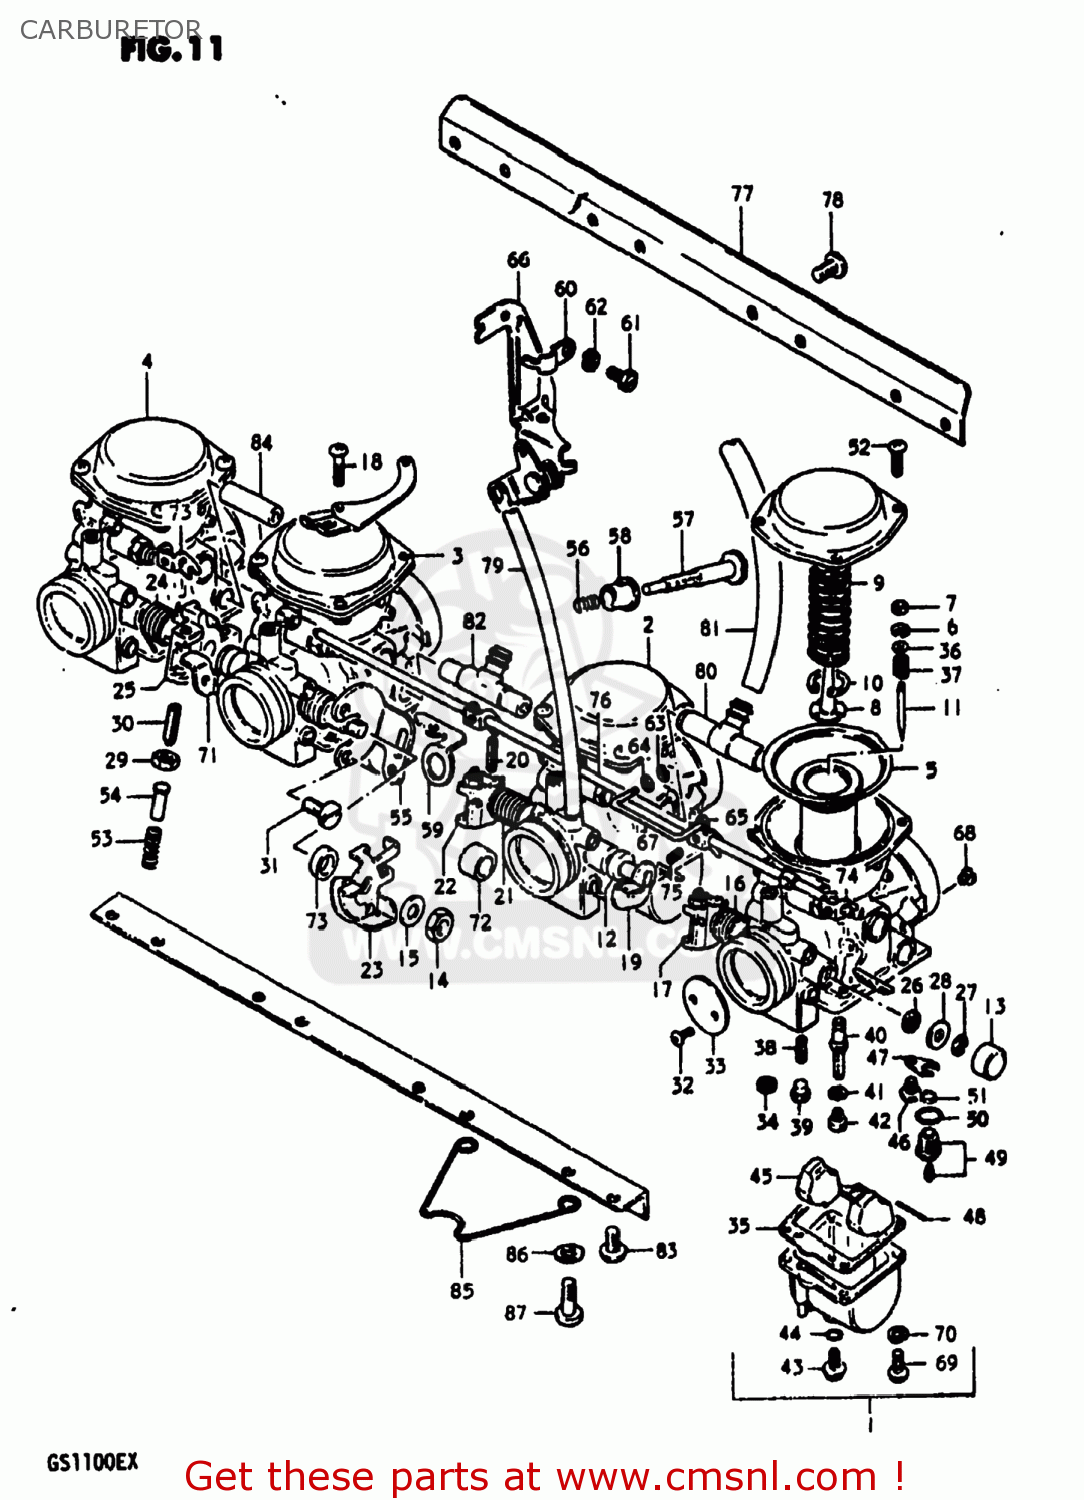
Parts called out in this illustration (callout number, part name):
1	CARBURETOR ASSEMBLY
2	CARBURETOR ASSEMBLY NO.2
3	CARBURETOR ASSEMBLY
4	CARBURETOR ASSEMBLY
5	DIAPHRAGM ASSEMBLY
6	CLIP,NEEDLE
7	RING
8	HOLDER,GUIDE
9	SPRING
10	E RING
11	NEEDLE,JET
12	GASKET
13	CAP
14	NUT
15	WASHER
16	SPRING,THROTTLE SHAFT
17	SHAFT,THROTTLE
18	SCREW
19	SHAFT,THROTTLE
20	PIN,THROTTLE SHAFT
21	SPRING,THROTTLE SHAFT
22	LEVER,THROTTLE SHAFT
23	LEVER ASSEMBLY,THROTTLE
24	SPRING,THROTTLE SHAFT
25	SHAFT,THROTTLE
26	SEAL
27	E RING
28	GASKET,THROTTLE SHAFT (NAS)
29	NUT
30	SCREW
31	SCREW
32	SCREW
33	VALVE,THROTTLE (BUTTERFLY)
34	GASKET (NAS)
35	GASKET,FLOAT CHAMBER (NAS)
36	WASHER
37	SPRING
38	JET,PILOT
39	PLUG,NEEDLE JET
40	JET,NEEDLE
41	WASHER,NEEDLE NOZZLE
42	JET,MAIN(107.5)
43	PLUG,DRAIN
44	GASKET (NAS)
45	FLOAT
46	SCREW
47	PLATE
48	PIN,FLOAT
49	VALVE ASSEMBLY,NEEDLE
50	O-RING,NEEDLE VALVE
51	FILTER
52	SCREW
53	SPRING,THROTTLE SCREW
54	PIN,THROTTLE LEVER
55	BRACKET,THROTTLE ADJUST
56	SPRING
57	SCREW
58	BUSH
59	BRACKET,THROTTLE ADJUST
60	BRACKET,STARTER
61	BOLT
62	LOCK WASHER
63	CAP,LEVER
64	SEAT,SPRING
65	LEVER ASSY
66	BRACKET
67	ROD,STARTER LEVER
68	JET
69	SCREW
70	LOCK WASHER
71	SHAFT,THROTTLE
72	RING
73	RING
74	LEVER
75	SCREW
76	SHAFT,STARTER
77	BRACKET
78	SCREW
79	HOSE
80	NIPPLE
81	NIPPLE
82	NIPPLE
83	SCREW 6X12
84	NIPPLE
85	CLAMP
86	WASHER
87	SCREW
